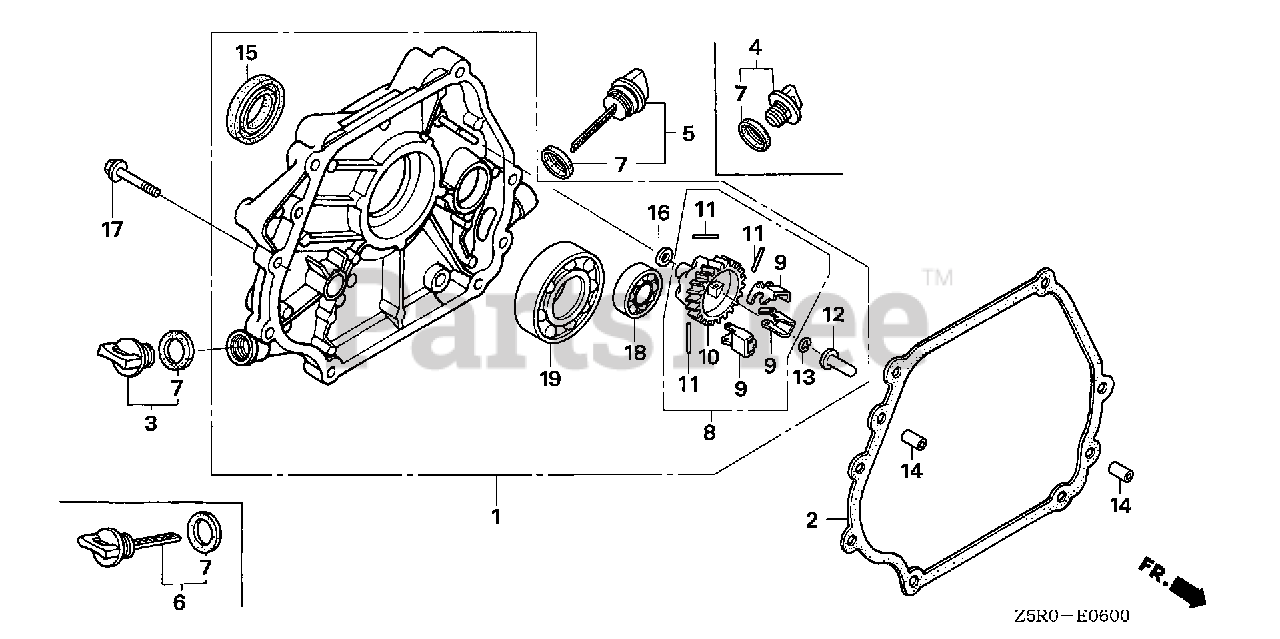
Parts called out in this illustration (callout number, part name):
1	COVER ASSY., CRANKCASE
2	GASKET, CRANKCASE COVER
3	CAP ASSY., OIL FILLER
5	CAP ASSY., OIL FILLER
7	GASKET, OIL FILLER CAP
8	GOVERNOR ASSY.
9	WEIGHT, GOVERNOR
10	HOLDER, GOVERNOR WEIGHT
11	PIN, GOVERNOR WEIGHT
12	SLIDER, GOVERNOR
13	CLIP, GOVERNOR HOLDER
14	PIN, DOWEL (8X12)
15	OIL SEAL (35X52X8)
16	WASHER, PLAIN (6MM)
17	BOLT, FLANGE (8X40) Use up to Engine SN 1003236.
18	BEARING, RADIAL BALL (6202)
19	BEARING, RADIAL BALL (6207)
